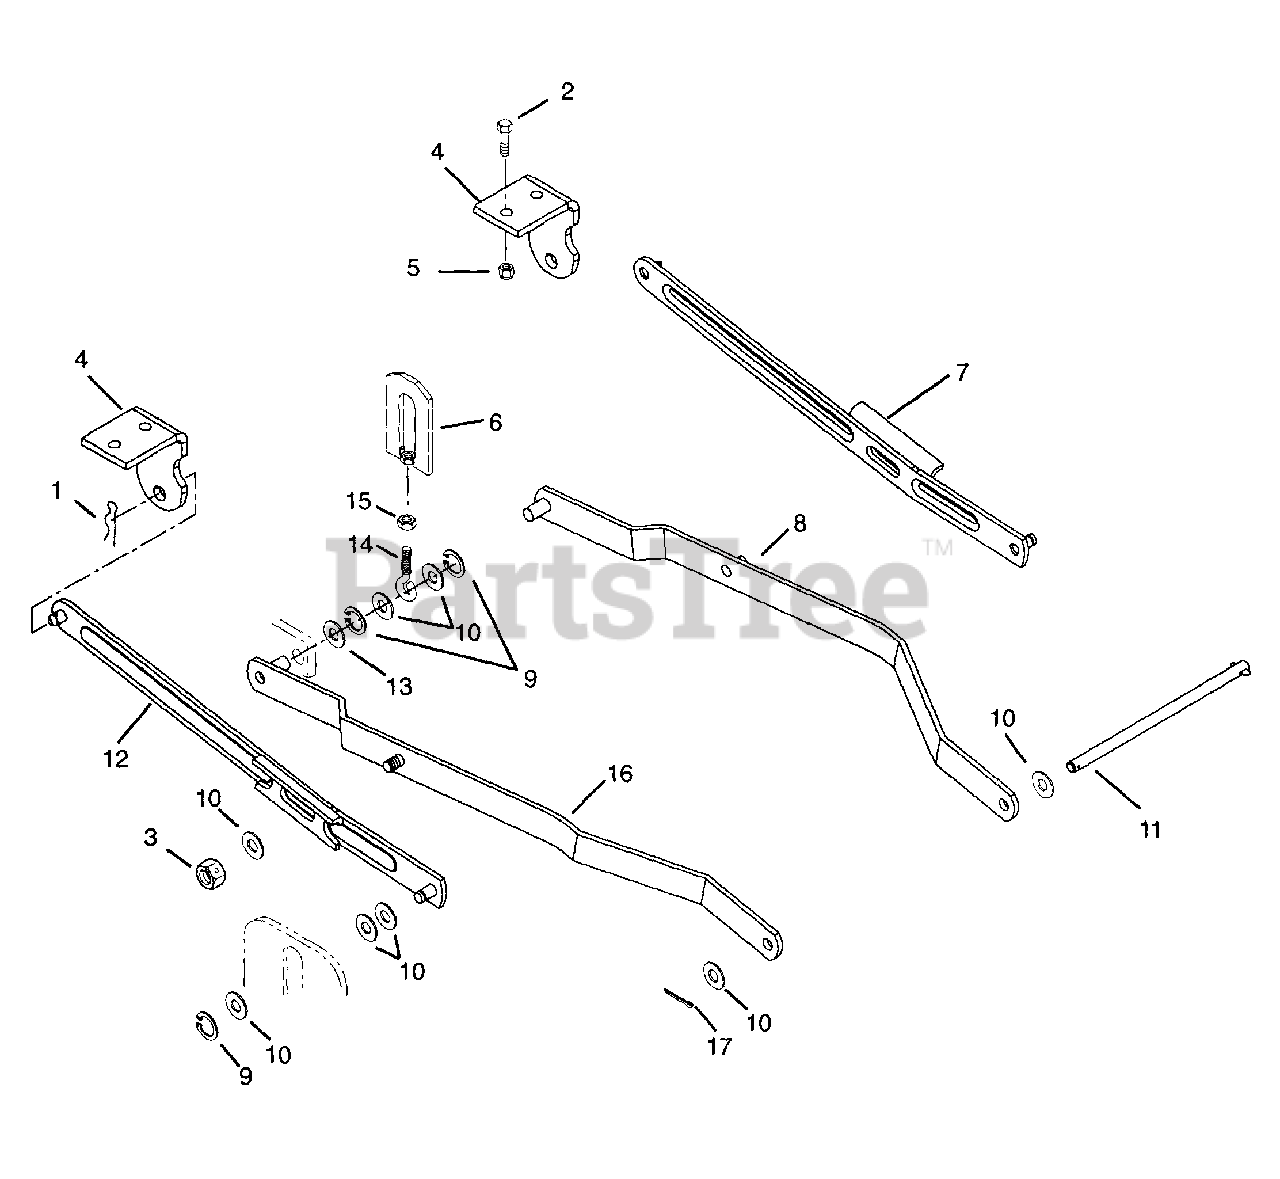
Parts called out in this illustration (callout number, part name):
1	PIN-HAIR EXT .12X.31X2.37 PL
2	BLT-HEX .38-16X1.00 PL GR5
3	NUT-LK-CTR .625-11 TYP N
4	REAR HANGER
5	NUT-LK-NYL .375-16 PL
6	LINK, ADJUSTMENT
7	REAR HANGER, L.H.
8	L.H. LIFT ARM
9	RG-RTNG-EXT .500X.050 (SNAP)
10	WSHR-FL-STL.656X1.312X.095 PL
12	REAR HANGER, R.H.
13	WSHR-FL-STL .531X1.250X.100 PL
14	HANGER
15	NUT-JAM .375-16 PL
16	R.H. LIFT ARM
17	PIN-COTR .12X1.0 PL
